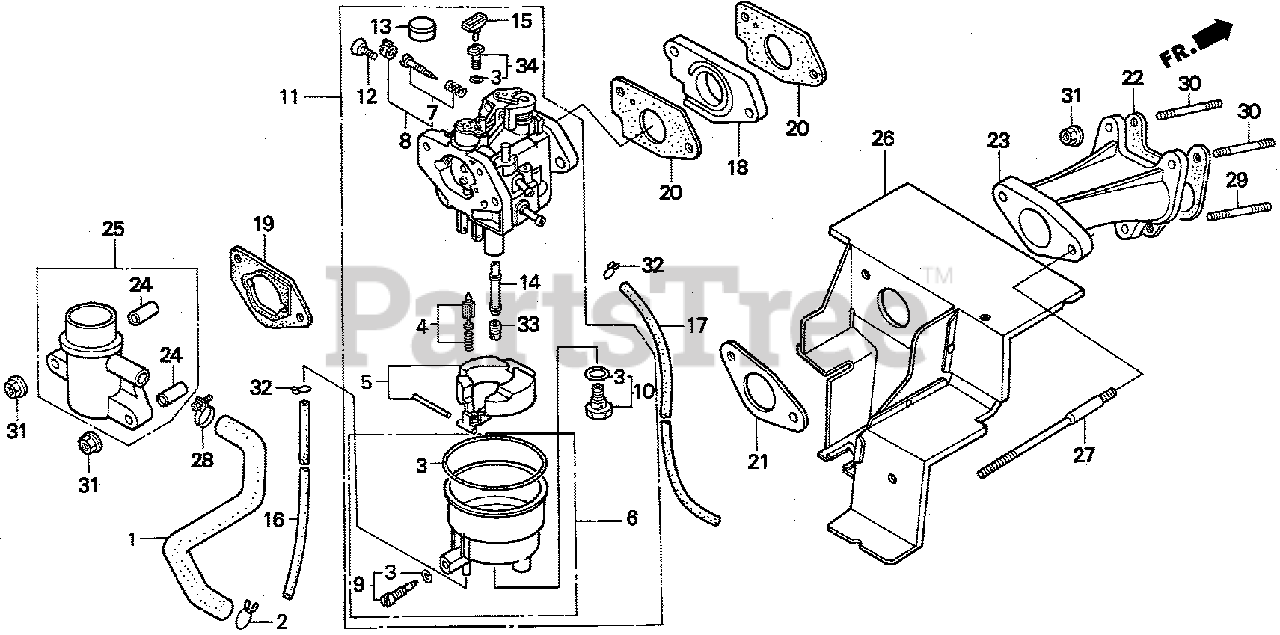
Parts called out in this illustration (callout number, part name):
1	TUBE, BREATHER
2	CLIP, BREATHER TUBE
3	GASKET SET
4	VALVE SET, FLOAT
5	FLOAT SET
6	CHAMBER SET, FLOAT
8	SCREW SET (CARBURETOR NO.)
9	SCREW SET, DRAIN
10	SCREW SET
11	CARBURETOR ASSY. (BE77A A)
12	SCREW, THROTTLE STOP
13	CAP, CHOKE LEVER DUST
14	NOZZLE, MAIN
15	COLLAR, SET
16	TUBE, FUEL DRAIN
17	TUBE, AIR VENT
18	INSULATOR, CARBURETOR
19	SPACER, CARBURETOR
20	GASKET, CARBURETOR
21	GASKET, INSULATOR
22	GASKET, IN. MANIFOLD
23	MANIFOLD, IN.
24	COLLAR, AIR CLEANER
25	ELBOW, AIR CLEANER
26	COVER, EX.
27	BOLT, STUD (8X123)
28	CLIP A18, TUBE
29	BOLT, STUD (6X32)
30	BOLT, STUD (6X28)
31	NUT, FLANGE (6MM)
32	CLIP, TUBE (B8)
33	JET, MAIN (#85)
33	JET, MAIN (#88)
33	JET, MAIN (#90)
34	JET SET, PILOT (#45)
